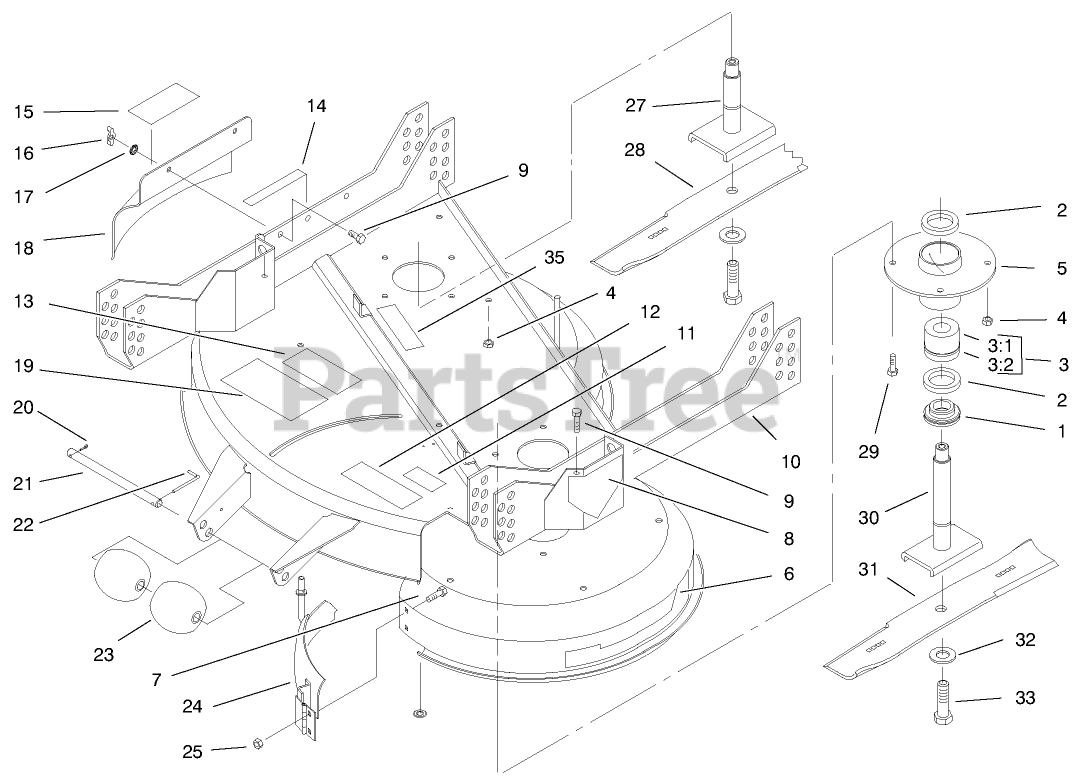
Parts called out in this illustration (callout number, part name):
1	SPACER
2	SEAL-OIL
3	BEARING ASM
3:1	BEARING ASM
3:2	SPACER-SET, MATCHED
4	NUT-LOCK, NI
5	SPINDLE HOUSING
6	DECAL - 37"
7	SCREW-CARRIAGE
8	DECAL-DANGER
9	SCREW-HH
10	DECK SUPPORT
11	Decal-Safety
12	DECAL - DISCHARGE DOOR
13	DECAL-TORQUE
14	DECAL-DANGER, DEFLECTOR
15	DECAL - DANGER
16	NUT-WING
17	WASHER-LOCK
18	Cover-Discharge
19	DECAL-DANGER, THROWN OBJECT
20	PIN-COTTER
21	SHAFT-ROLLER
22	PIN-SPECIAL
23	ROLLER
24	Cover-Front
25	NUT-KEPS
27	SHAFT-SPINDLE
28	Blade
29	SCREW-HH
30	SHAFT-SPINDLE
31	Blade
32	WASHER-LOCK
33	SCREW-BLADE
35	DECAL-DANGER
